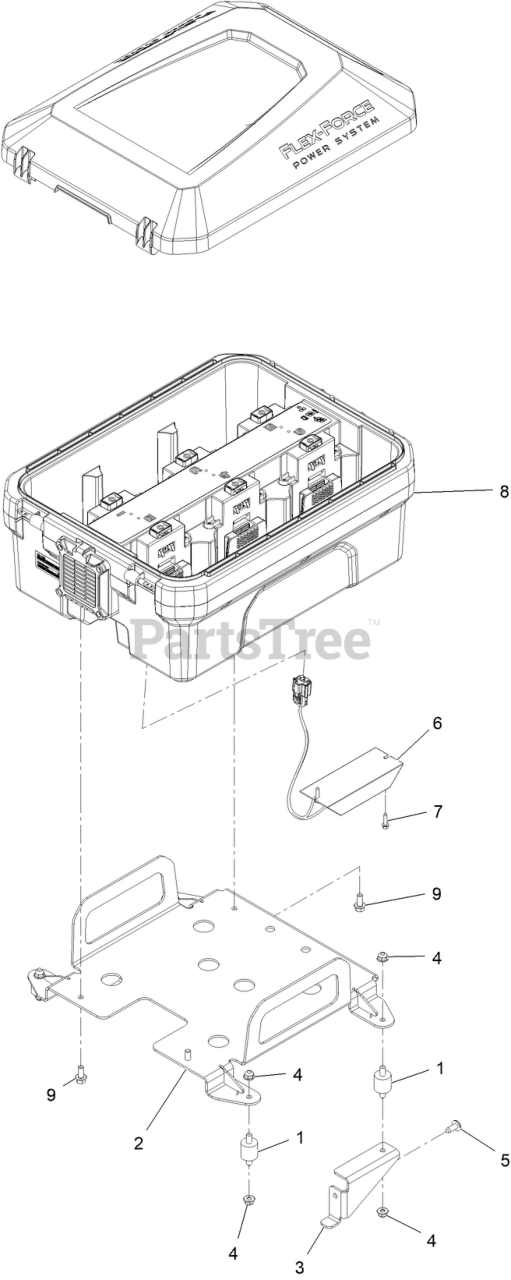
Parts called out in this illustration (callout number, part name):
1	ISOLATOR-1 IN OD (5/16-18)
2	BATTERY MOUNT ASM
3	MOUNT-BOX, REAR
6	RESISTOR-REGEN
7	SCREW-HWH THD ROLL ZCT+W
8	Box-Battery, ASM
9	SCREW-HHF
